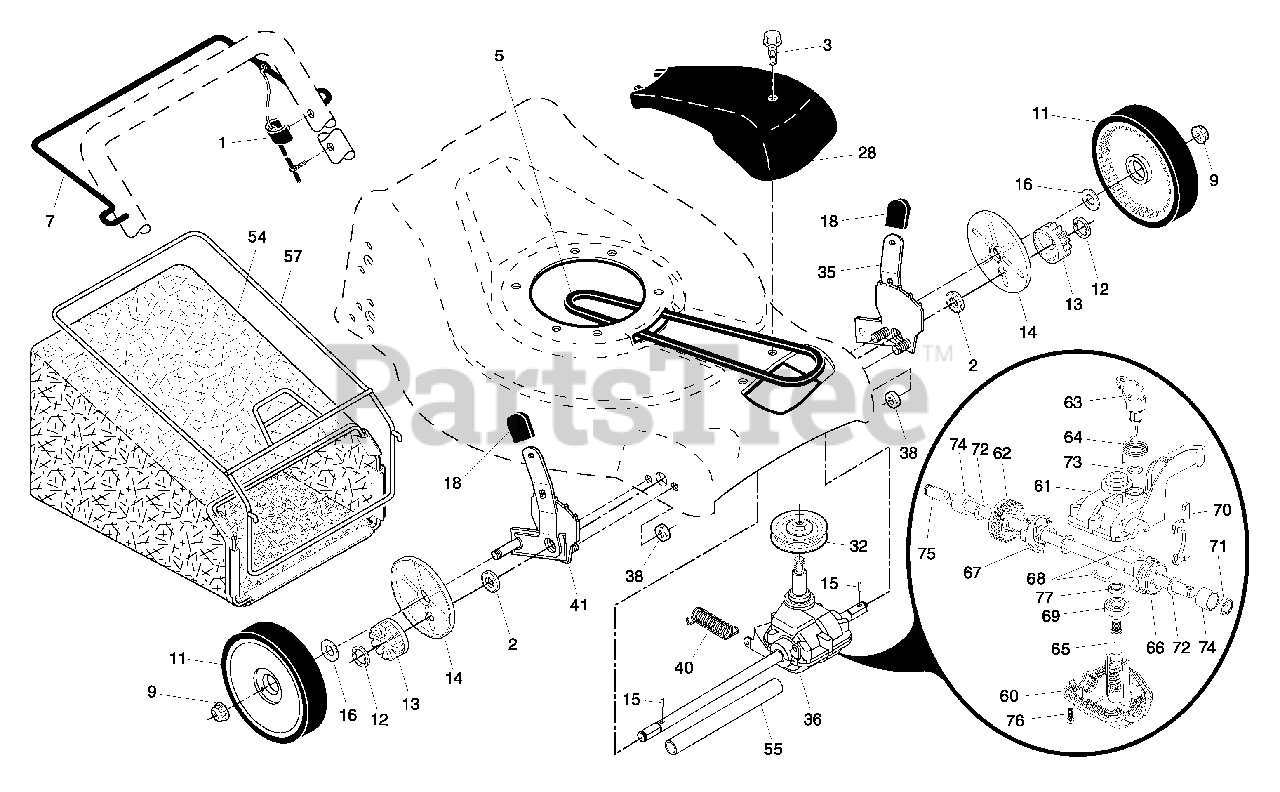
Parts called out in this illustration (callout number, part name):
1	Control Cable Assembly
2	Bearing, Wheel Adjuster
3	Pan Head Tapping Screw #10-24 x 2-3/4
5	V-Belt
6	Spring Retainer
7	Bar, Drive Control
9	Nut, Hex, Flangelock
11	Wheel & Tire Assembly
12	E-Ring
13	Pinion
14	Dust Cover
15	Pawl, Drive
16	Washer 1/2 x 1-1/2 x .134
18	Selector Knob
28	Dive Cover
32	Pulley, Drive
35	Kit, Wheel Adjuster, LH
36	Gear Case Assembly, Complete
38	Locknut, Hex 1/4-20
40	Spring
41	Kit, Wheel Adjuster, RH
54	Grassbag
55	Driveshaft Cover
57	Frame, Grassbag
60	Case, Lower
61	Case, Upper
62	Gear, 27 Teeth
63	Lever, Clutch
64	Spring, Return
65	Shaft, Input
66	Dog, Movable
67	Dog, Fixed
68	Wire, Formed
69	Bearing, Ball
70	Fork, Shift
71	Seal, Output Shaft
72	Washer
73	Seal, Case
74	Bushing
75	Shaft, Output
76	Screw
77	Seal, Input Shaft
